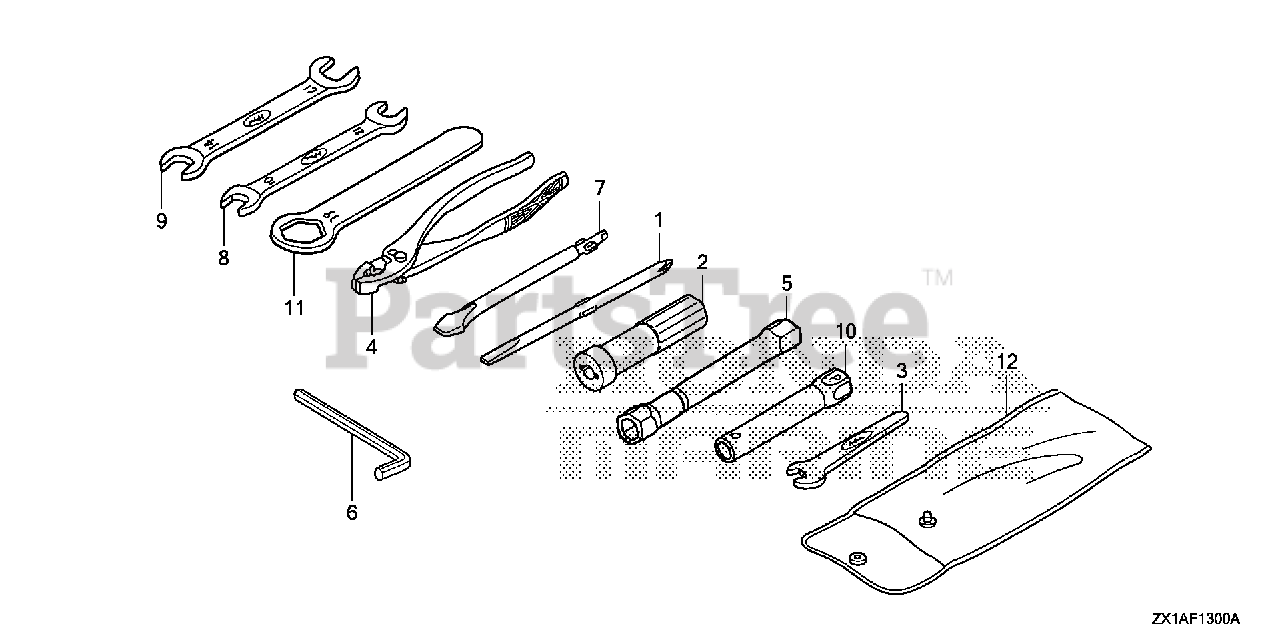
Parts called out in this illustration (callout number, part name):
1	SCREWDRIVER (NO.2 PHILLIPS -)
3	WRENCH (8MM) (OPEN END) (NOT AVAILABLE)
4	PLIERS (135) (RIKEN)
5	WRENCH, PLUG
6	WRENCH, HEX. (6MM)
7	SCREWDRIVER, CHECK BOLT
8	WRENCH (10X12) (OPEN END)
9	WRENCH (14X17) (OPEN END)
10	WRENCH, BOX (P16X17)
11	WRENCH, EYE (19MM)
12	BAG, TOOL (230MM)
